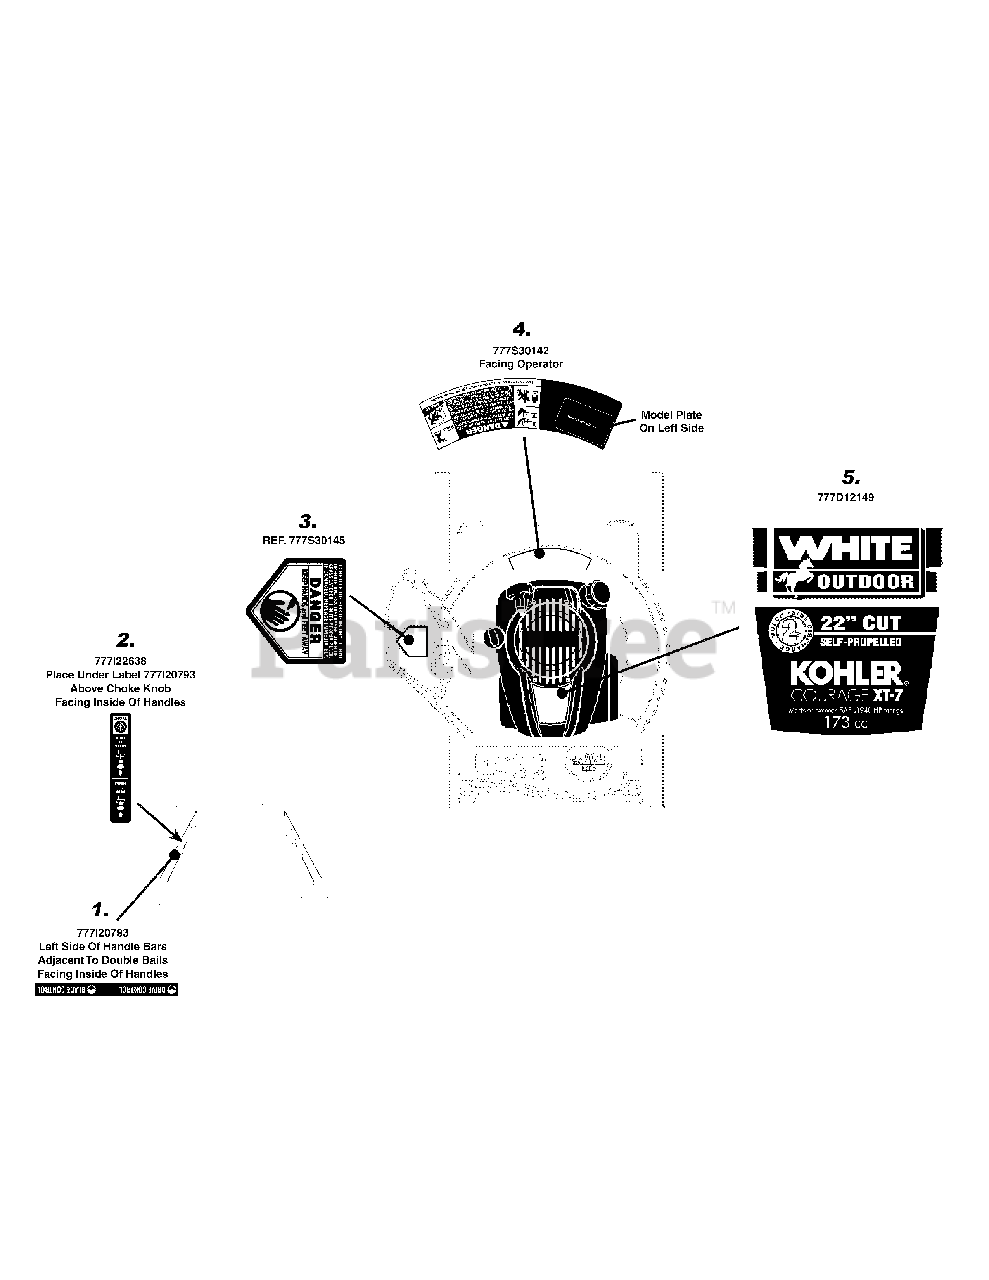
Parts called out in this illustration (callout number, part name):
2	LABEL-MOWER HANDLE:CHOKE START/RUN
3	LABEL
4	LABEL-DANGER CURVE
